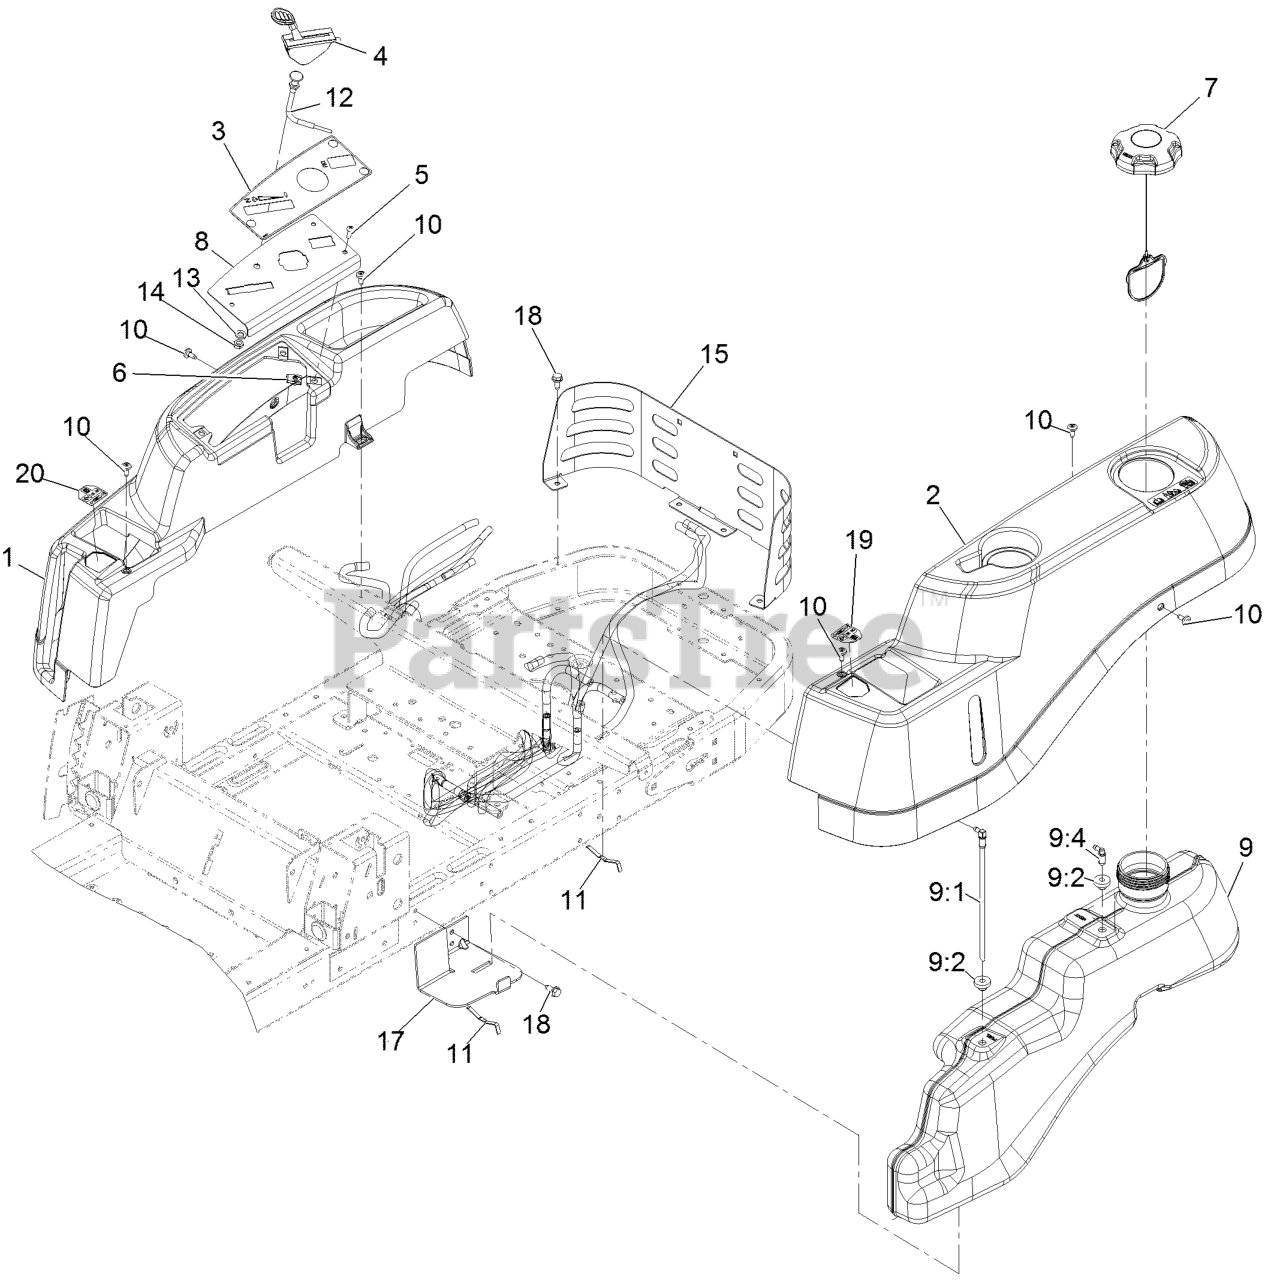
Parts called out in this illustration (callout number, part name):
3	DECAL-PANEL, CONTROL
4	CABLE-THROTTLE
5	SCREW-PRH
6	Nut-Retainer-Panel 1/4-20
8	PLATE-CONTROL
9	FUEL TANK ASM
9:1	CONNECTOR-ELBOW, 90 DEG
9:2	BUSHING
9:4	FITTING-PLASTIC
10	SCREW-SHOULDER
11	SPRING
12	CABLE-CHOKE
13	WASHER-LOCK
14	NUT-HJ
15	GUARD-REAR
17	SUPPORT-TANK, FRONT
18	Screw-HWH 5/16-18 X 3/4 Tf
19	DECAL-LEVER, CONTROL (LH)
20	DECAL-LEVER, CONTROL (RH)
